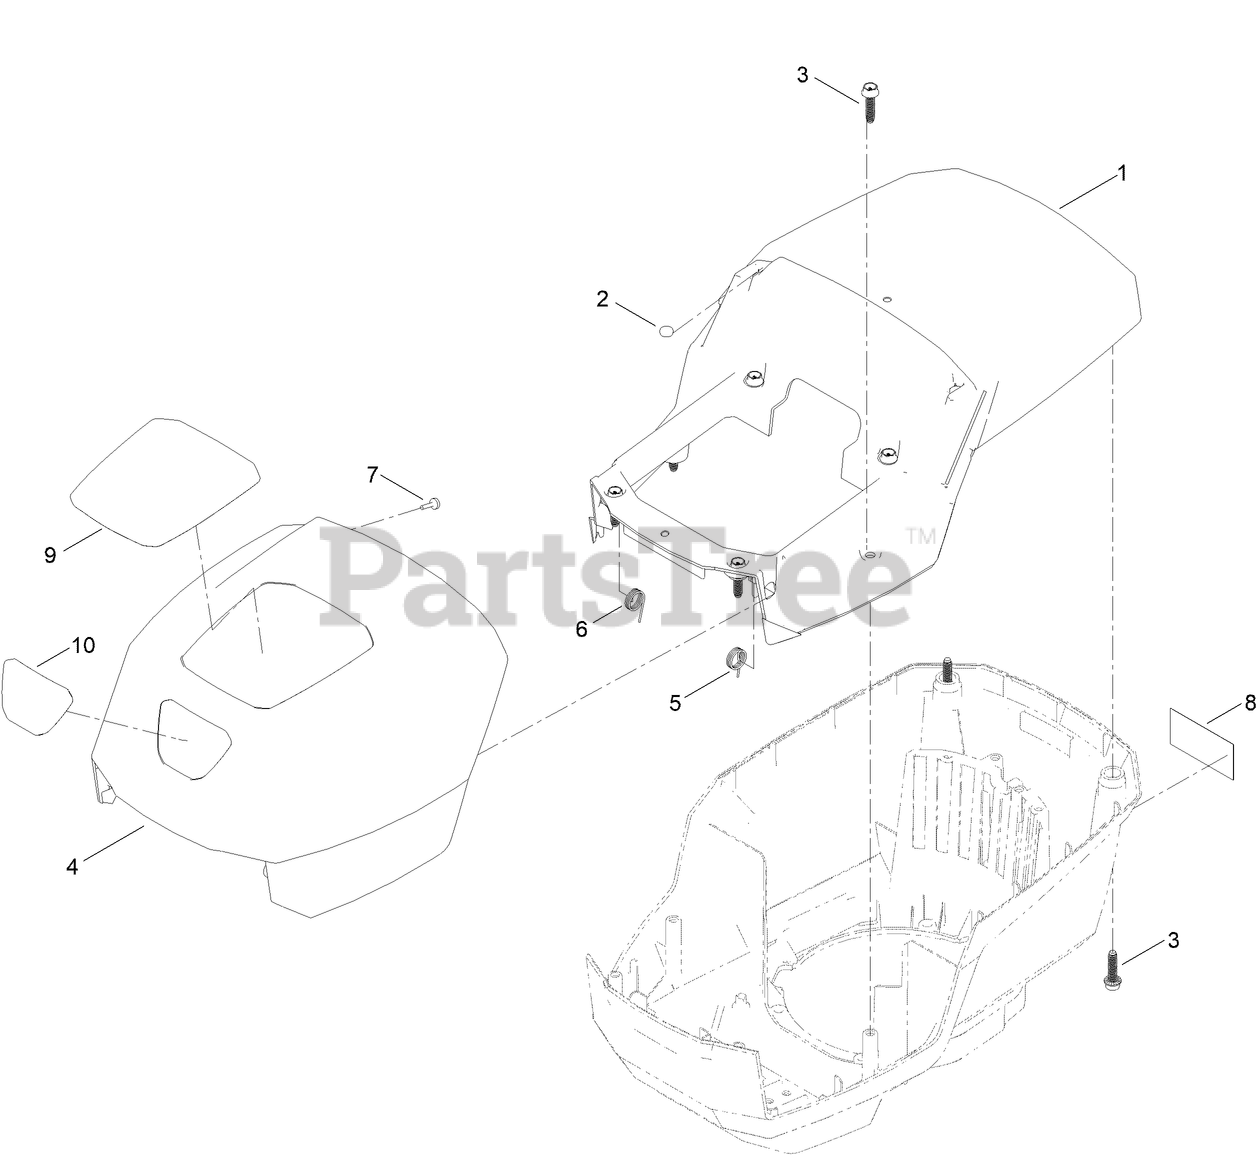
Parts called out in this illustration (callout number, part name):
1	SHROUD-UPPER
2	MAGNET
3	SCREW-FLANGE, PLASTIC
5	SPRING-LH
6	SPRING-RH
7	SCREW-PPH
8	LABEL-PART/SERIAL
9	DECAL - COVER TOP 60V
10	DECAL - COVER FRONT
